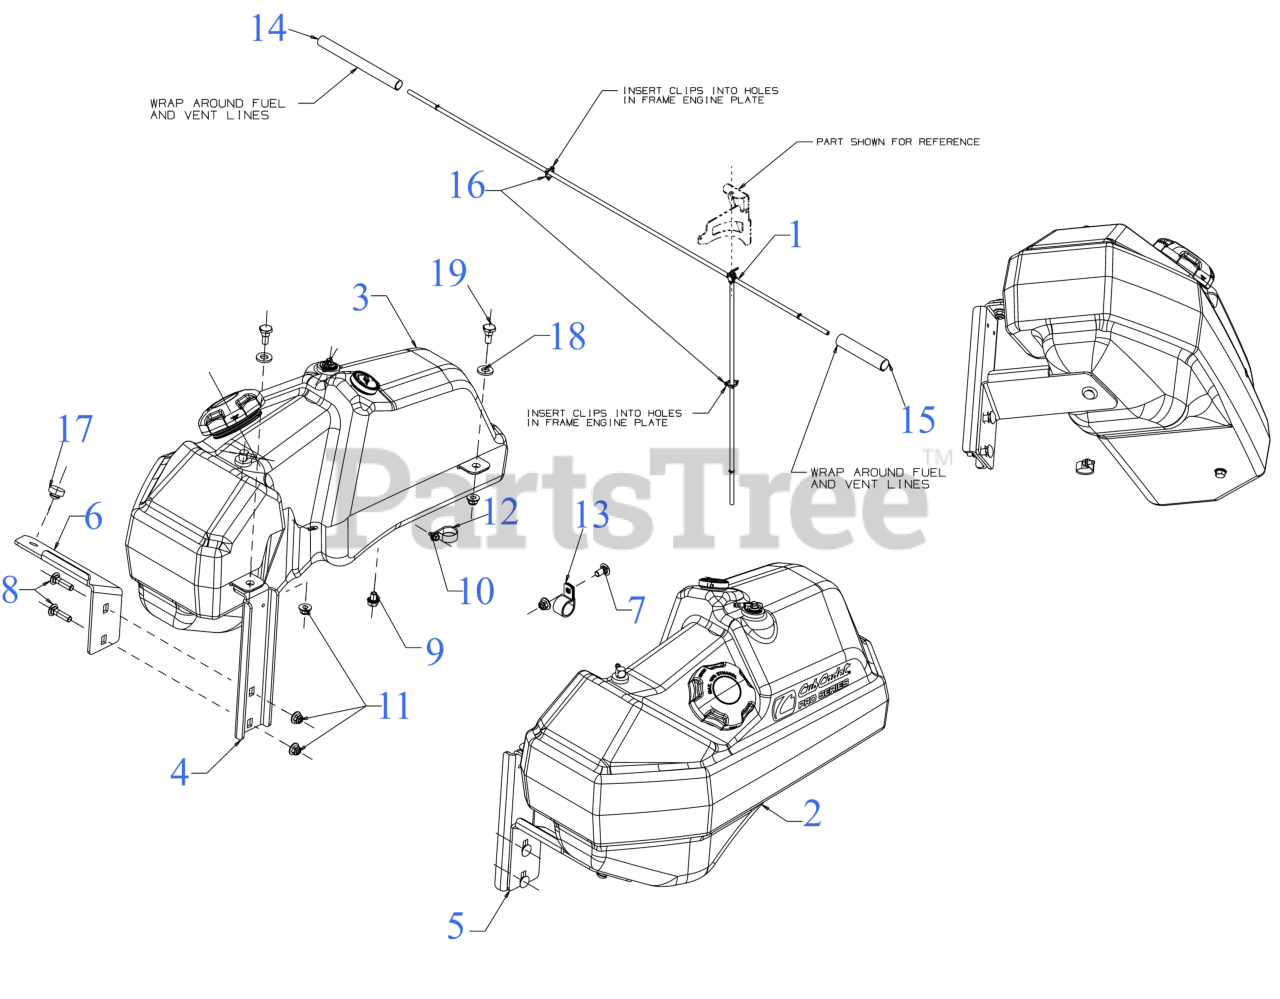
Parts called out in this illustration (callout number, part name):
1	FUEL HOSE W/VALVE
2	FUEL TANK (7.25 GAL) (RH)
2	TANK ASM (RH) (7.25 GAL)
3	FUEL TANK (7.25 GAL) (LH)
3	TANK ASM (LH) (7.25 GAL)
4	FUEL TANK MOUNTING BRACKET
7	CARRIAGE BOLT 3/8-16 x .750 GR5
8	CARRIAGE BOLT 3/8-16 x 1.50
9	SCREW 3/8-16 x .500 GR5
10	SCREW 1/4-20 X.500
12	DRAIN HOSE CLAMP
13	HOSE CLAMP 1.0"
14	WRAP AROUND SLEEVE 14"
15	WRAP AROUND SLEEVE 8"
17	RUBBER BUMPER 1.000 x .313
18	FLAT WASHER .510 x 1.000 x .125
19	SHOULDER SCREW .498 DIA x .340
